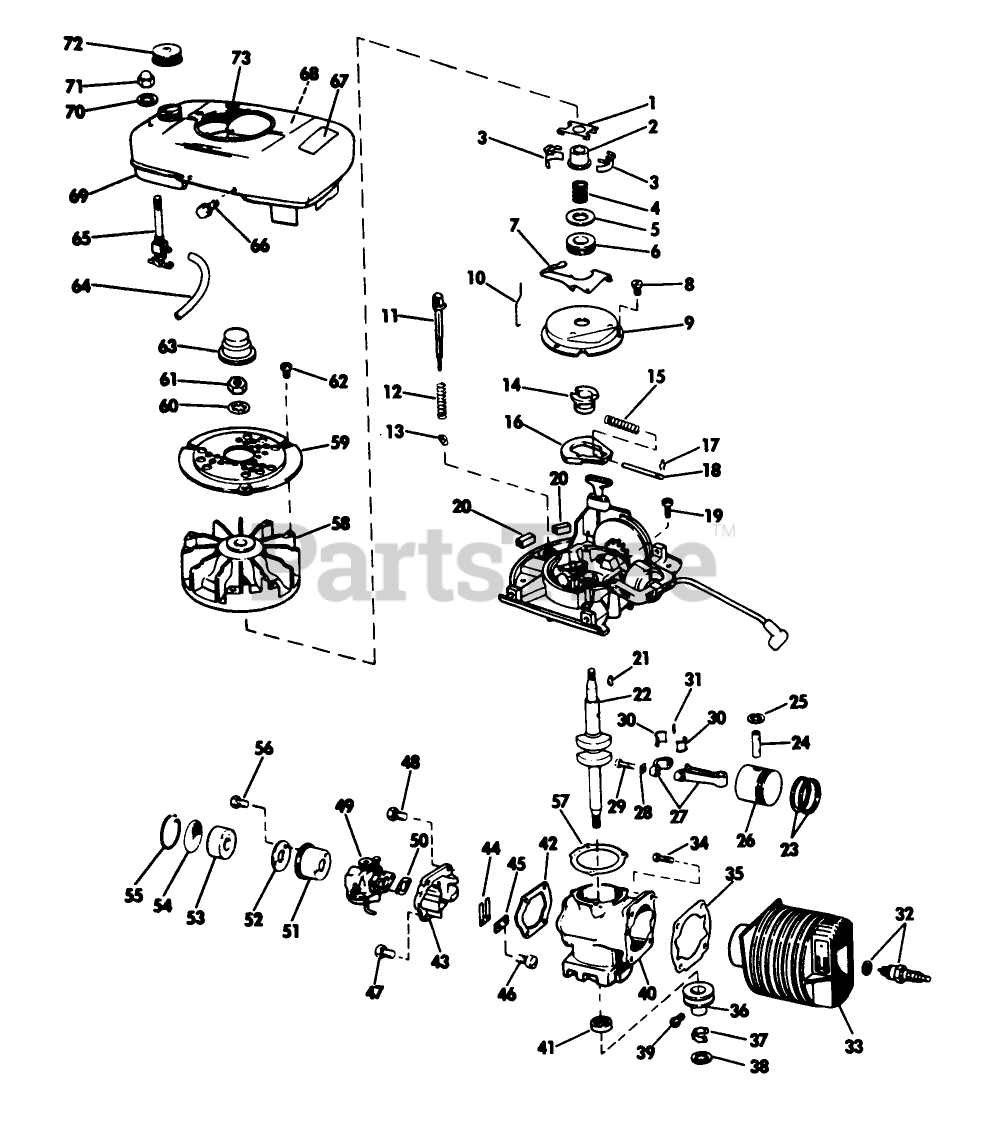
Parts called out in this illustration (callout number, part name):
2	COLLAR S
6	THRUST COLLAR S
7	LEVER-GOVERNOR S
8	SCREW S
9	DUST COVER S
12	SPRING S
14	SPARK ADV. S
15	SPARK ADV. SPRING S
16	FLYWEIGHT S
17	SPARK ADJ. SPRING
18	PIN,SPARK ADV. S
25	RING-RETAINING
28	Lockplate
30	LINER ASM
35	GASKET S
45	PLATE-BACKUP, REED
47	SCREW S
48	SCREW S
50	GASKET S
52	BACK-UP PLATE
53	ELEMENT
57	GASKET S
65	VALVE&SCREEN SM
66	SCREW S
71	PALNUT S
